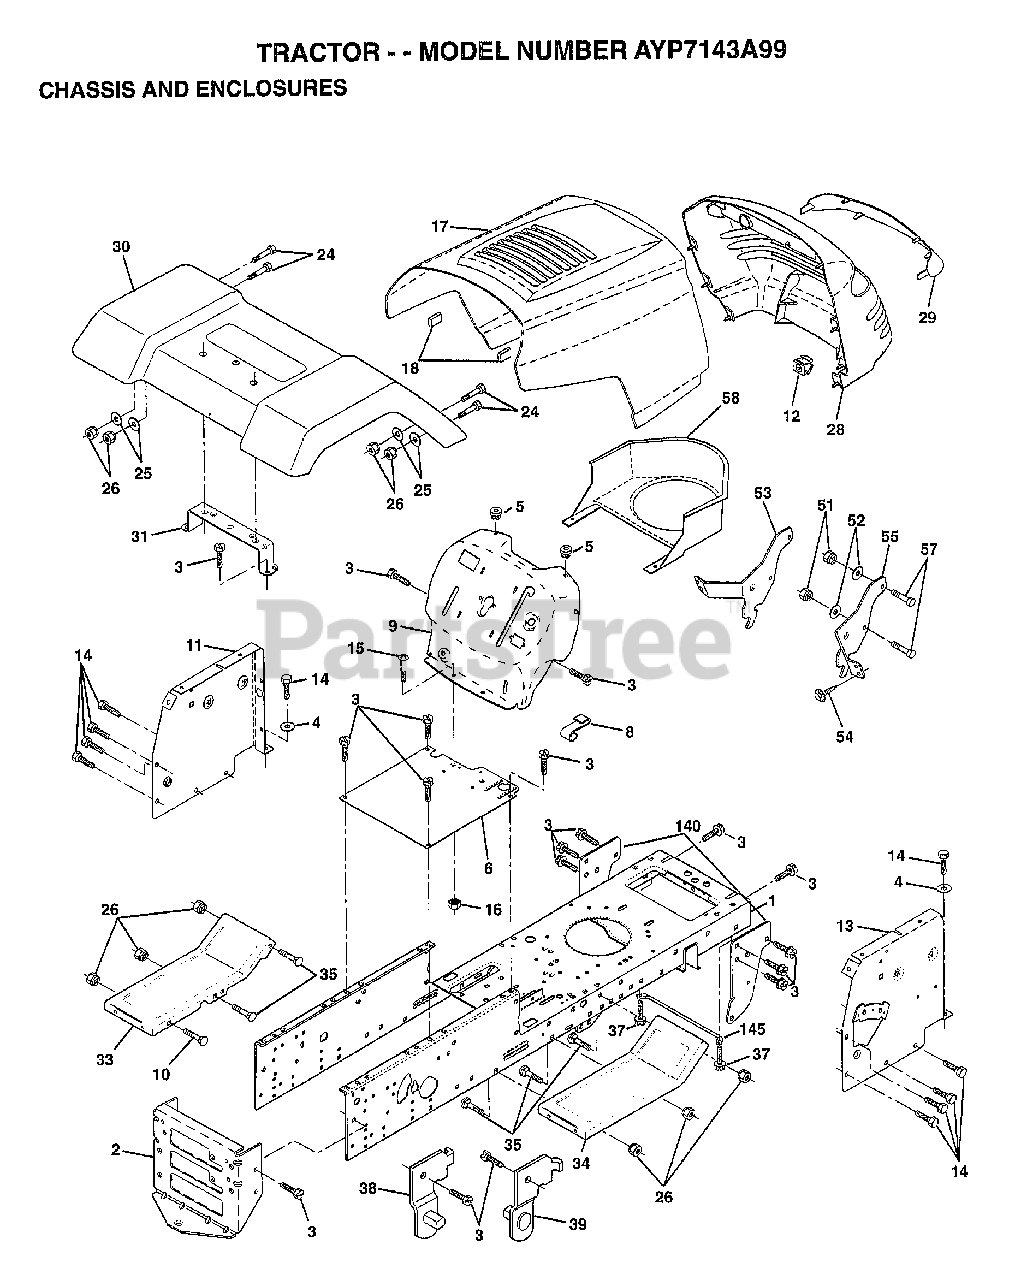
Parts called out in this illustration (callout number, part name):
1	CHASSIS.STAMPING
3	SCREW
4	WASHER
5	BUMPER-HOOD/DASH
6	SADDLE-SILKSCREEN
8	CLIP.RETAINER
9	DASH SILKSCREEN
11	"PANEL-DASH,LH"
12	CLIP.TINNERMAN
14	SCREW LT
15	SCREW
17	HOOD.STEEL.ASSY
24	BOLT
25	WASHER
26	NUT
28	GRILLE-MS428
29	LENS.GRILLE.PRIVATE LABEL
30	FENDER BRACKET
31	BRKT FENDER
33	FOOTREST LH
34	FOOTREST RH
35	BOLT
37	SCREW LT
38	BRACKET ASM LH
39	BRACKET ASM RH
51	NUT
52	WASHER
53	BRACKET.GRILLE.LH
54	SCREW.HEX.WS.HD
55	BRACKET.GRILLE.RH
58	AIR DUCT
140	BRKT SUSPENSION
145	"ROD POVOT,CHASSIS"
